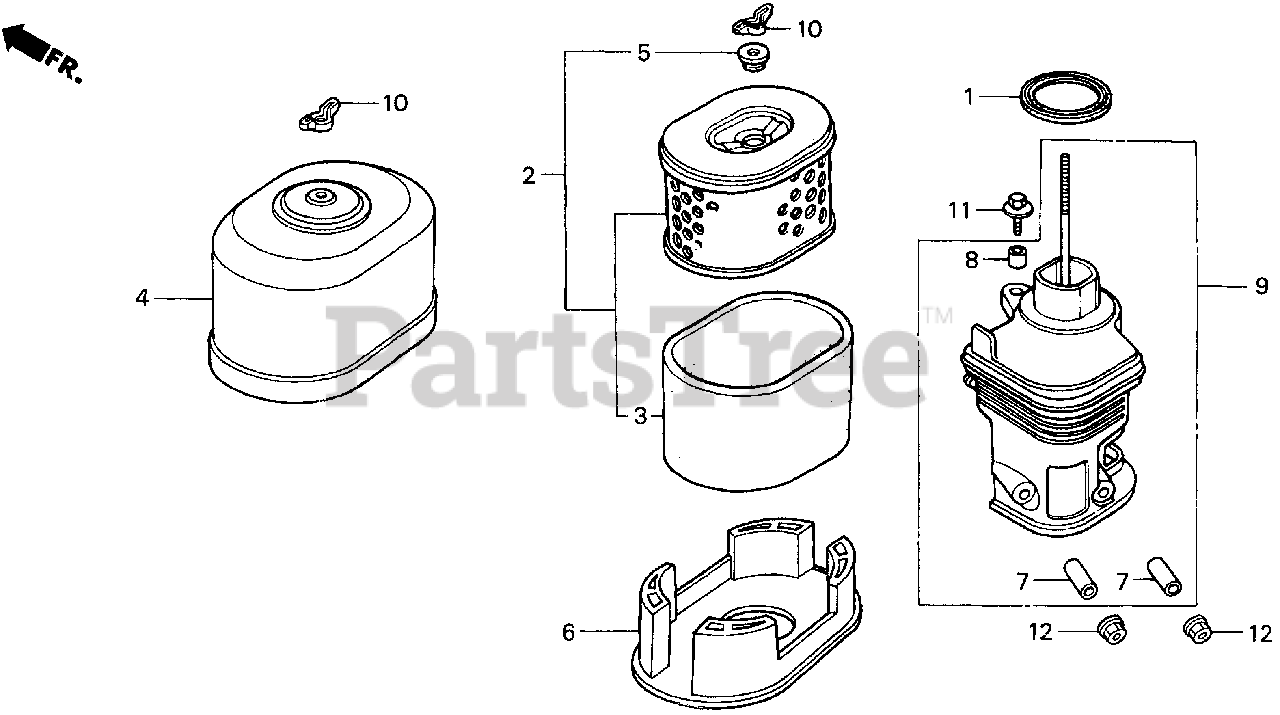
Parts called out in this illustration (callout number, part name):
1	GASKET, ELBOW
2	ELEMENT, AIR CLEANER
3	FILTER (OUTER)
4	COVER, AIR CLEANER (STD)
5	GROMMET, AIR CLEANER
6	NOSE, MUFFLER
7	COLLAR, AIR CLEANER
8	COLLAR B, AIR CLEANER
9	ELBOW, AIR CLEANER
10	WINGNUT, TOOL BOX SETTING
11	BOLT-WASHER (6X22)
12	NUT, FLANGE (6MM)
